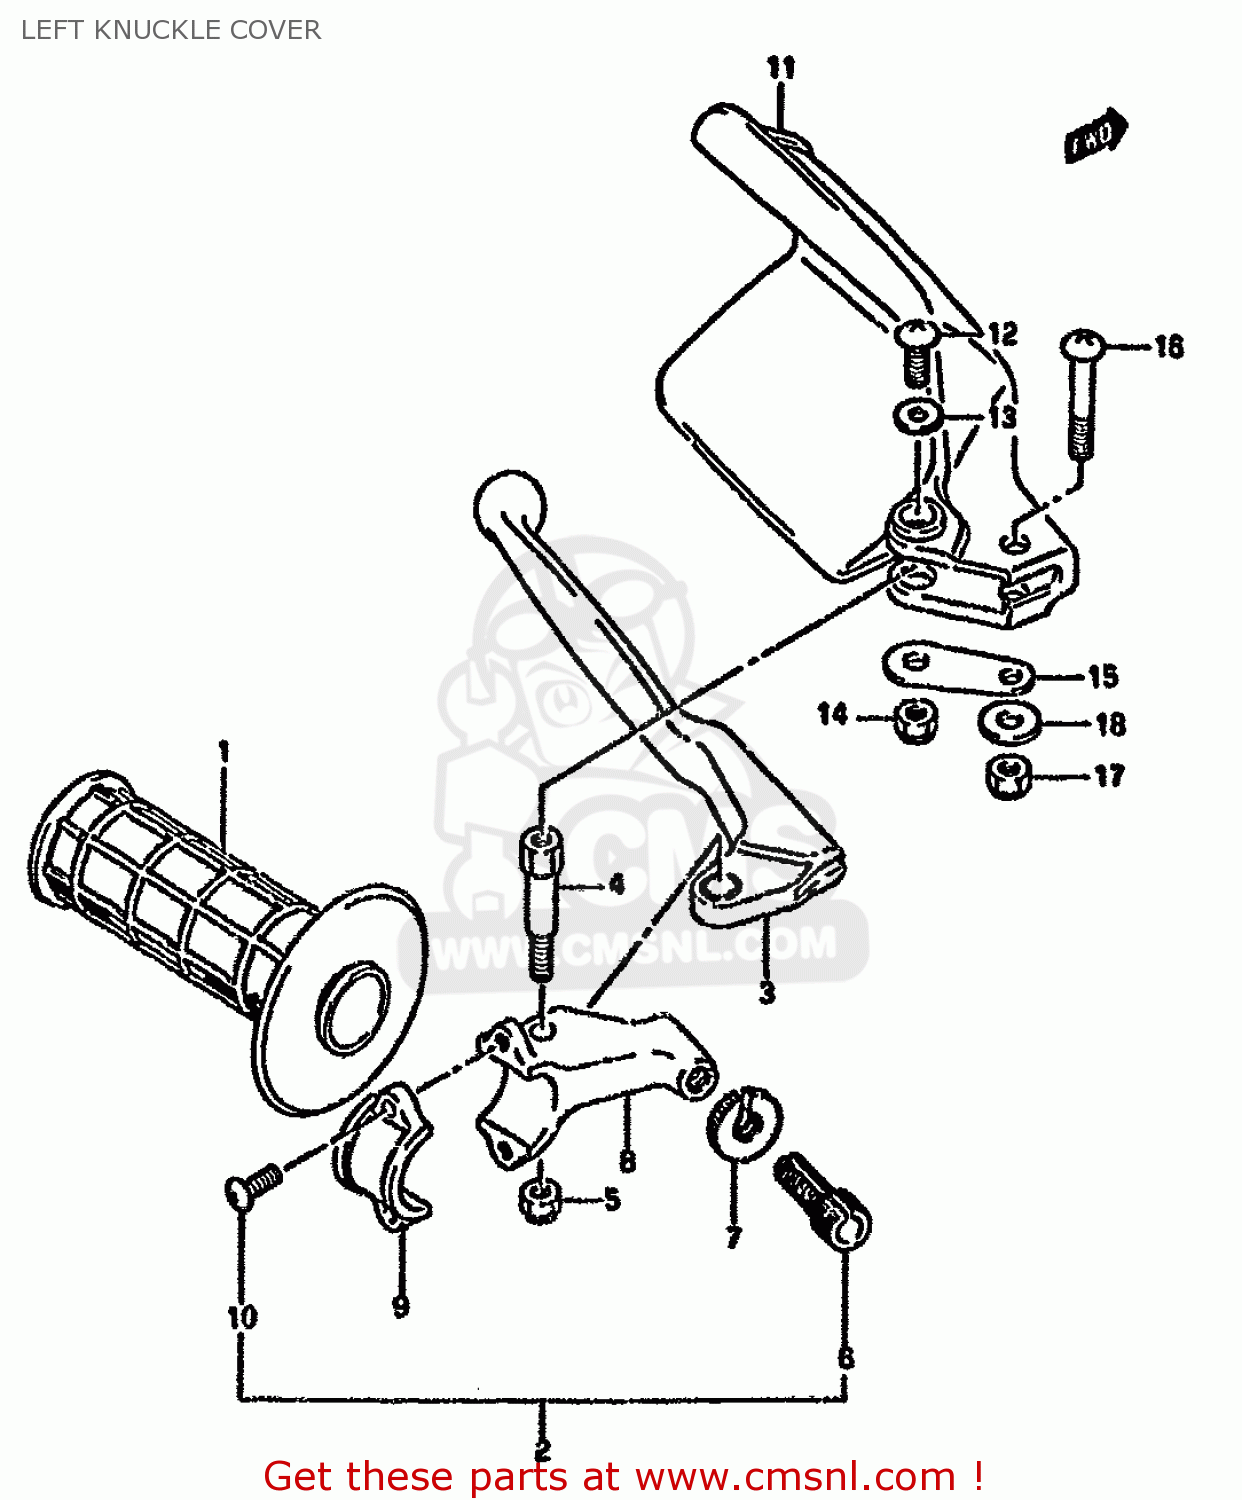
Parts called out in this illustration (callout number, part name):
1	GRIP,L
2	LEVER ASSY,CLUTCH
3	LEVER,CLUTCH
4	BOLT,LEVER SET
5	NUT 6MM
6	ADJUSTER,CABLE
7	NUT,LOCK
8	HOLDER,CLUTCH LEVER
9	BRACKET,CLUTCH LEVER HOLDER
10	SCREW(5X14)
11	COVER,KNUCKLE,L
12	SCREW
13	WASHER (5.5X16X1.2)
14	NUT 6MM
15	PLATE,KNUCKLE COVER,L LWR
16	SCREW(6X35)
17	NUT 6MM
18	WASHER (6.5X17X1.6)
